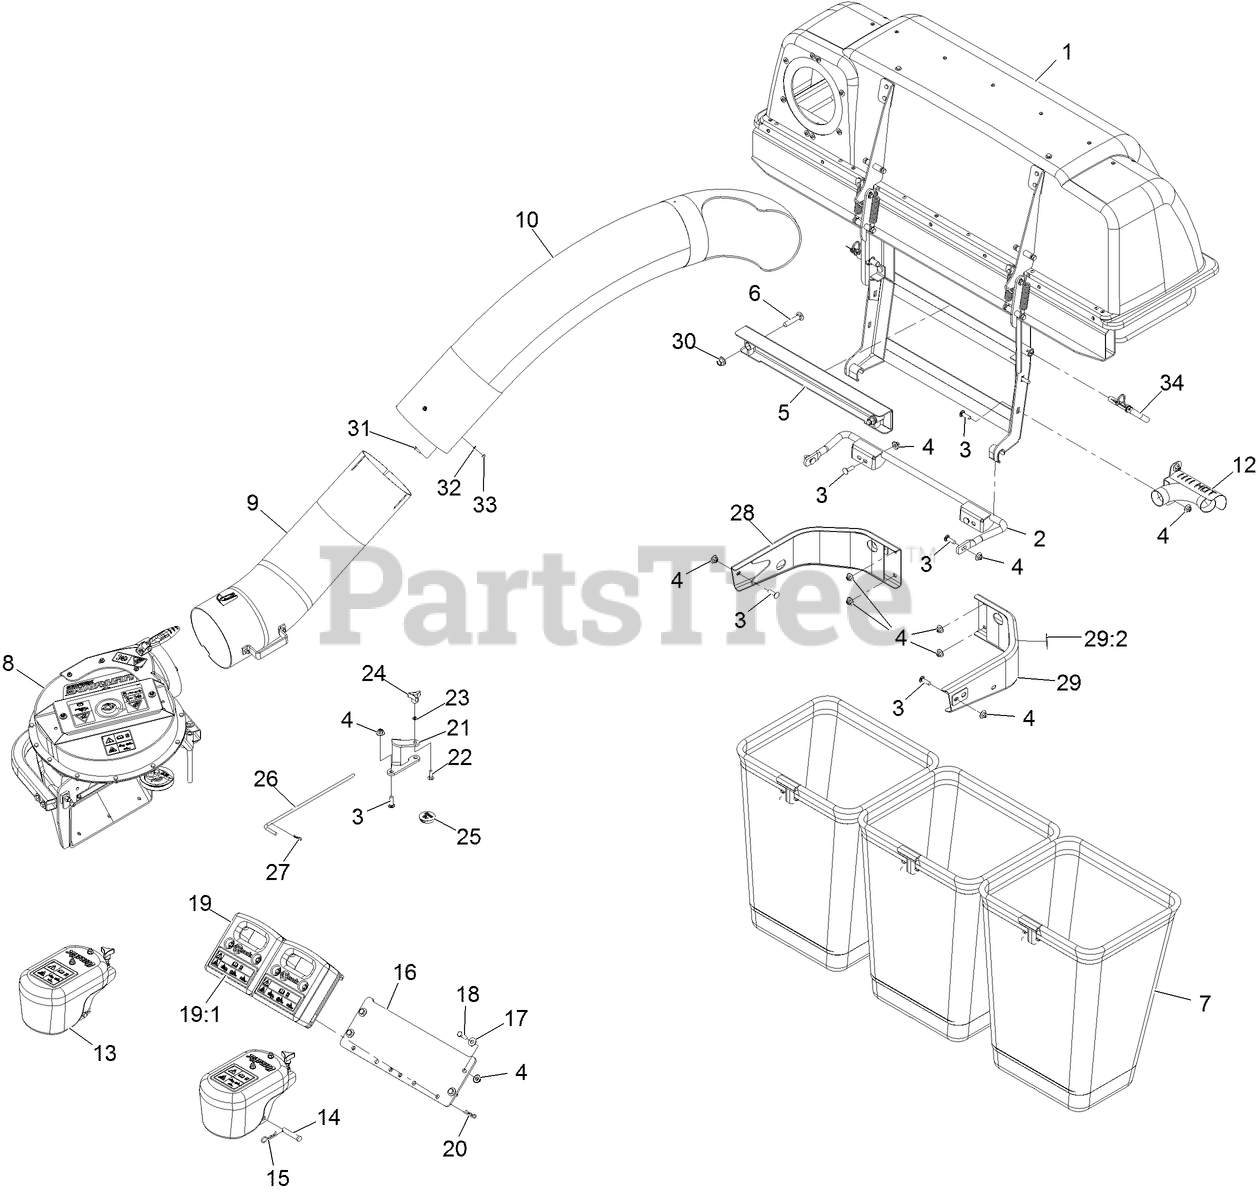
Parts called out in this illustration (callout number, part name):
1	ASM,Hood Uv 3 Bag
2	MOUNT-BAGGER, LOWER
3	Bolt-Carriage 3/8-16 X 1 1/4
4	Nut-Nyloc 3/8-16 Flg
5	MOUNT-BAGGER, UPPER
6	SCREW-CARR
7	BAG AND FRAME ASM
8	ASM, BLOWER LARGE - SVC ONLY
9	LOWER TUBE ASM
10	TUBE-UPPER
12	EXHAUST DIVERTER ASM
13	ASM,CASTER WEIGHT
14	PIN-CLEVIS
15	PIN-COTTER
16	PLATE,WEIGHT ASM MOUNT
17	WASHER-FLAT
18	SCREW-HH
19	ASM,CAST WEIGHT
19:1	DECAL-WARNING WEIGHT
20	PIN-HAIR
21	BRACKET,BELT COVER
22	BOLT-CARR
23	RING-RETAINING, BOLT
24	KNOB-3 PRONG
25	PLUG, BLACK NYLON 1.75
26	PIN,CHUTE PIVOT
27	PIN-COTTER
28	BUMPER-RH
29	LH BUMPER ASM
29:2	DECAL-WARNING
30	Nut-Lock 1/2-13
31	SCREW-HWH
32	WASHER-FLAT
33	NUT-LOCK, NI
34	PIN-MOUNT, BAGGER
